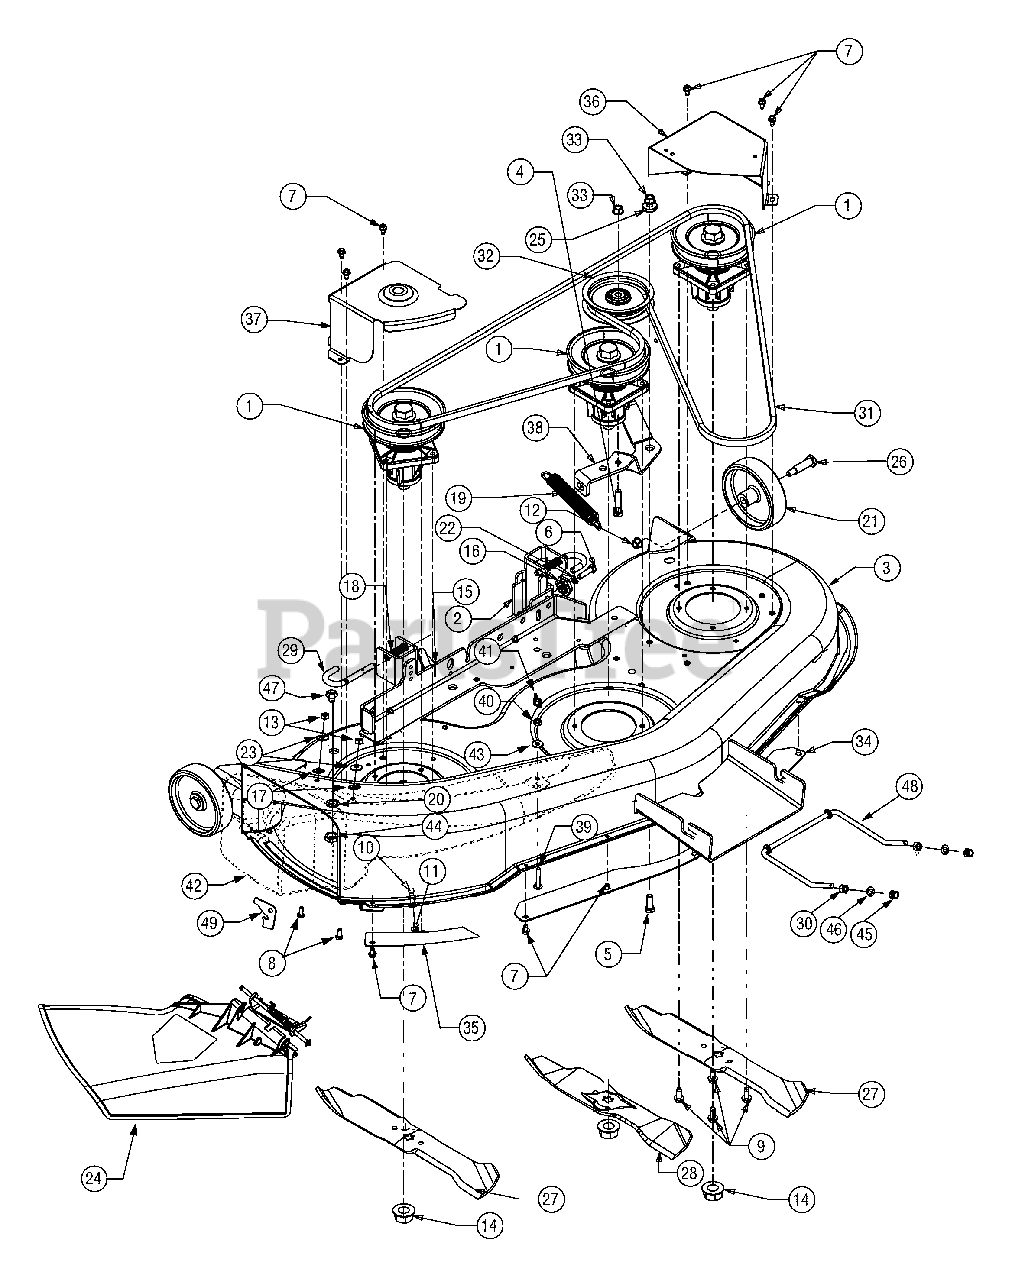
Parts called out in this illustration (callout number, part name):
1	Spindle Assembly
4	Screw, 3/8-16, 1.75
5	Hex Cap Screw, 3/8-16, 1.00, Gr5, Std
6	Screw, 5/16-18, 1.25, Gr5
7	Screw, Hx. Wash. Hd. Tapp, 1/4-20, 0.5
8	Screw, Hex Cap, 1/4-20,.620, Gr5
9	Self-tapping Screw, 5/16-18 x.75
10	Pin, Grass catcher
11	Nut, Nylon Lock, 1/4-20
12	Flange Lock Nut, 3/8-16
13	Nut, Hex, 1/4-20, Gr5
14	Nut, Flange, 5/8-18
15	Cotter Pin, 1.0
16	Deck Adjustment Gear
17	Push Nut
18	Compression Spring, 1.75
19	Extension Spring, 7.33
20	Lock Washer, 5/8
21	Deck Wheel
22	Washer, Lock, 5/16, Regular Duty
23	Washer, Belleville,.265 x.75 x.062
24	Chute Assembly, Side Discharge
25	Spacer, Shoulder, 1.00 x.38 x.38
26	Shoulder Screw
27	Blade, 16.28, Star, 3-in-1
28	Blade, 14.88, 3-in-1
29	Rod, Handle, Deck Release.375 Dia
30	Hex Nut, 1/2-13
31	Belt, V-Type
32	Idler Pulley, 4.25
33	Flange Lock Nut, 3/8-16
39	Screw, 1/4-20, 1.50
40	Nut, Hex, 1/4-20, Gr5
41	Nut, Wing, 1/4-20
42	Mulch Plug
43	Washer, Flat,.28 X.74 X.063
44	Nut, Hex, M16-1.5
45	Hex Lock Nut, 1/2-13
46	Flat Washer,.51 x 1.12 x.06
47	Plug, M16 x 1.5
48	Front Deck Adjustment Rod
49	Chute Stop
